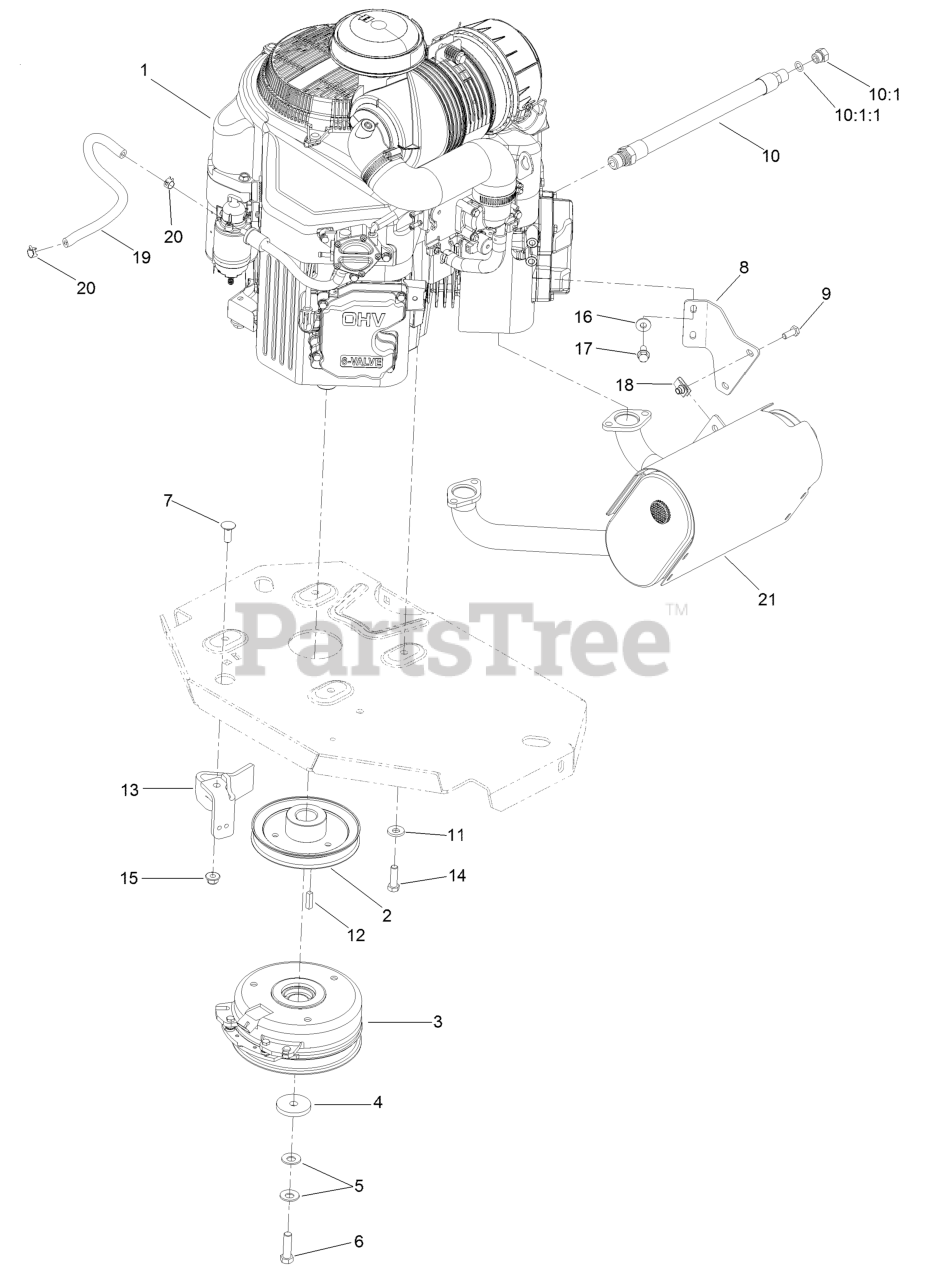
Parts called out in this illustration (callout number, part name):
2	SHEAVE
3	CLUTCH KIT
4	WASHER-CLUTCH
5	WASHER-SPRING
6	SCREW-HH 7/16-20 X 1 1/2 W/LOCTITE
7	SCREW-CARR
8	BRACKET-MUFFLER
9	SCREW-HH
10	ENGINE OIL DRAIN HOSE ASM
10:1	PLUG-HH
10:1:1	O-RING
11	WASHER-BELLEVILLE
13	CLUTCH-ANCHOR
14	SCREW-HH
15	NUT-HF, NI
16	WASHER-SPRING
17	SCREW-HHF
19	HOSE-FUEL
20	CLAMP-HOSE
21	MUFFLER
